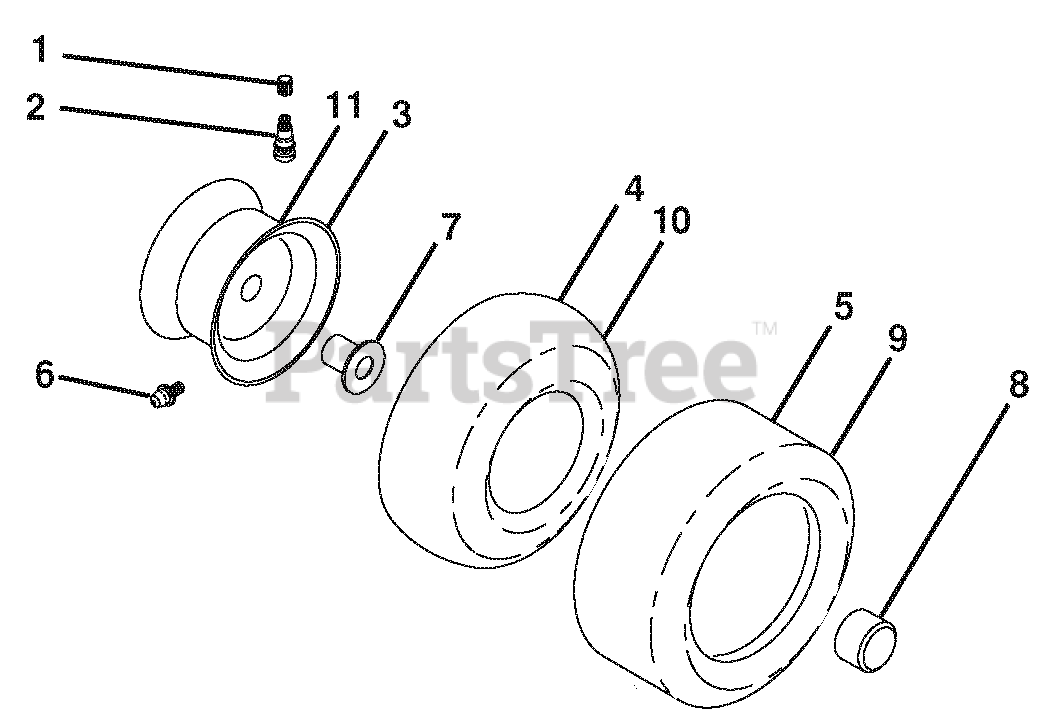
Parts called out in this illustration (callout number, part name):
1	CAP.VALVE.TIRE
2	STEM.VALVE
3	RIM ASSEMBLY 6" FRONT
4	TUBE, FRONT(SERVICE ITEM ONLY)
5	TIRE.F.TS.15 X 6.0 - 6.SERVICE
6	FITTING, GREASE
7	BEARING FLANGE
8	CAP AXLE (FRONT WHEEL ONLY)
9	TIRE.R.TS.20 X 8-8.C.SERVICE
10	TUBE, REAR
11	RIM ASSEMBLY 8" REAR
